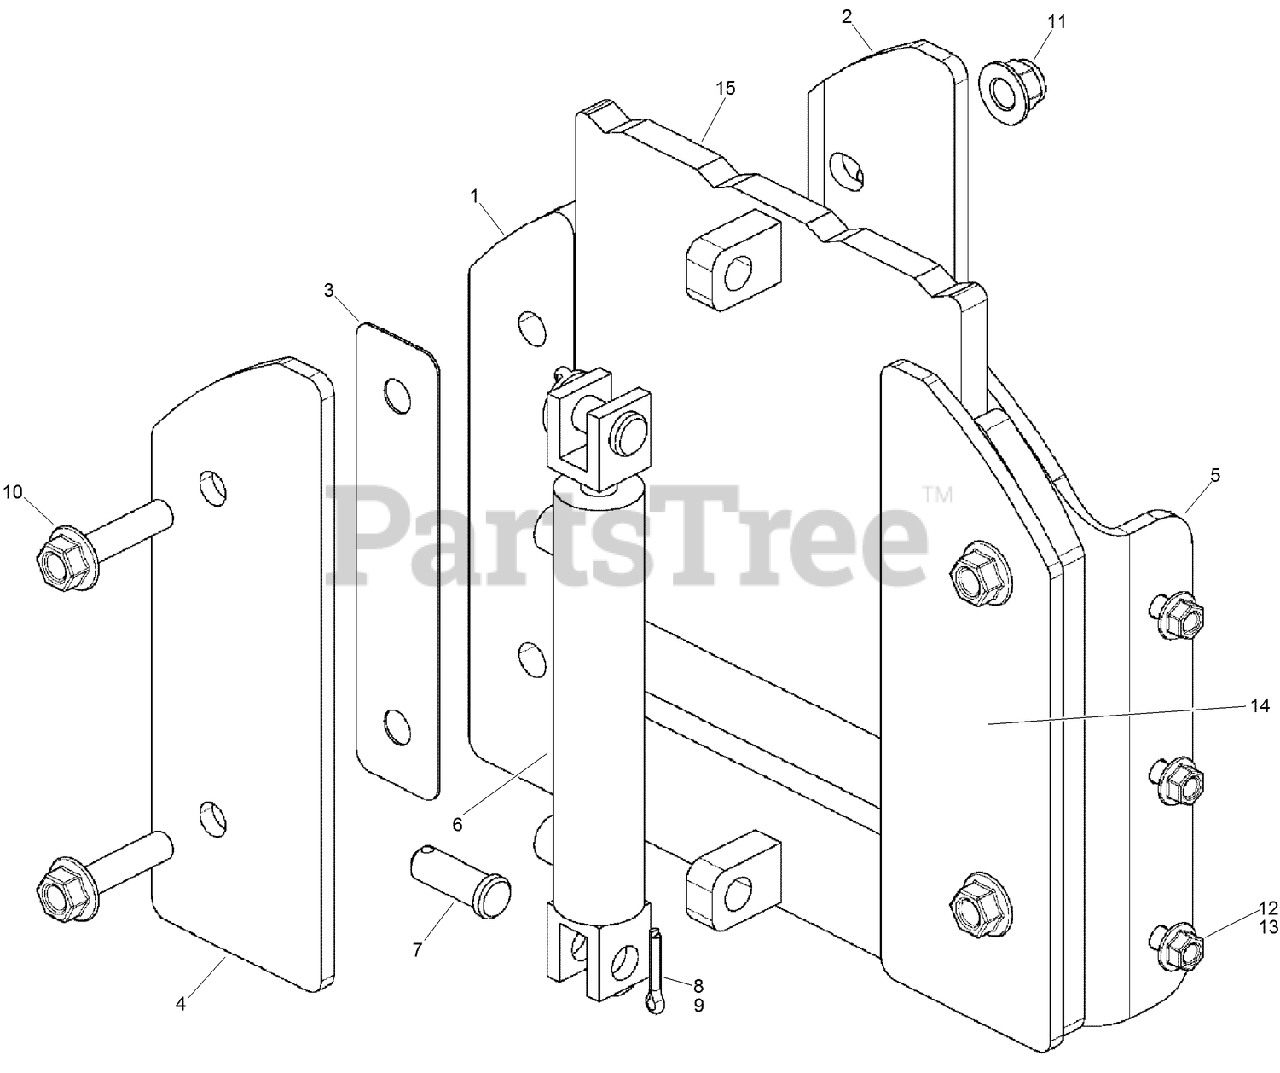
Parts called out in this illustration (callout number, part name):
1	PLATE - Elevator, Cylinder Lift Point
2	PLATE - Elevator
3	PLATE - Elevator
4	PLATE - Elevator
5	PLATE - Elevator
6	HYD CYLINDER ASM
7	PIN - Clevis
8	PIN - Cotter, 0.250 x 1.25 in ZN
10	SCREW-HHF
11	NUT-HHF
12	SCREW-HHF
13	NUT-HHF, LOCK
14	FITTING-Lube 1/4-28 Tpr SAE-LT .54 Long
15	PLATE - Elevator, Slide / Pipe Lift
